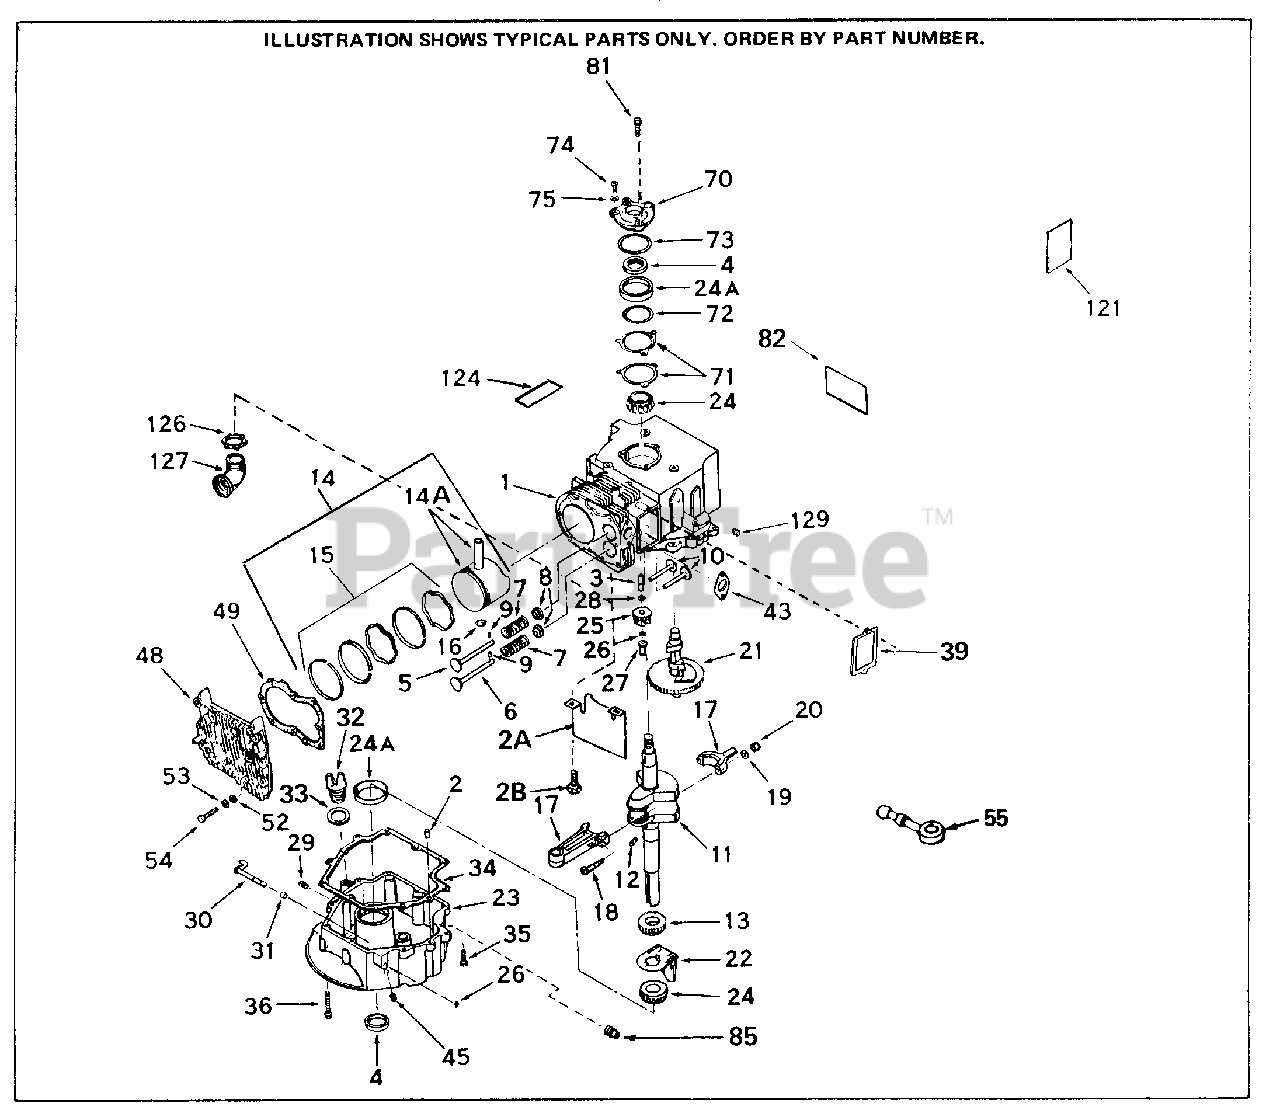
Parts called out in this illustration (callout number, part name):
1	"Cylinder (Incl. 2,2A,2B,3,4,82) 3-5/1 6" Bore
2	Dowel Pin
2A	Oil Baffle Not used in early product ion
2B	Screw, 10-24 x 1/2" Not in early pro d.
3	Shaft, Mechanical governor
4	Seal, Oil
5	Intake Valve (Std.)
5	Intake Valve (1/32" OS) (Incl. 8)
6	Exhaust Valve (Std.)
6	Exhaust Valve (1/32" OS) (Incl. 8)
7	Spring, Valve
8	Cap, Valve spring (Std.)
8	Cap, Valve spring (1/32" OS)
9	Pin, Valve spring retaining
10	Lifter, Valve
11	Crankshaft Incl. 12, 13, 22, 24 & 24 A
12	Pin, Crankshaft gear
13	Gear, Crankshaft
14	Piston, Pin & Ring Set (Std.) 3-5/16 " Bore
14	Piston, Pin & Ring Set (.010" OS)
14	Piston, Pin & Ring Set (.020" OS)
14	Piston, Pin & Ring Set (.040" OS)
14A	Piston & Pin Ass'y. (Incl. 16)(Std.) 3-5/16"
14A	Piston & Pin Ass'y. (Incl. 16) .010" OS
14A	Piston & Pin Ass'y. (Incl. 16) .020" OS
14A	Piston & Pin Ass'y. (Incl. 16) .030" OS
14A	Piston & Pin Ass'y. (Incl. 16) .040" OS
15	Ring Set (Std.) (3-5/16" Bore)
15	Ring Set (.010" OS)
15	Ring Set (.020" OS)
15	Re-Ringing Set, Piston
15	Ring Set (.030" OS)
15	Ring Set (.040" OS)
16	Ring, Piston pin retaining
17	Connecting Rod Ass'y. (Incl. 18,19,20 ) (Std.)
17	Connecting Rod Assy. (Incl. 18,19,20) . 010" OS
17	Connecting Rod Assy. (Incl. 18,19,20) . 020" OS
18	Screw, Connecting rod
20	Nut, Connecting rod, 5/16-24
21	Camshaft (MCR)
22	Dipper, Oil
23	Flange, Mounting (Incl. 4, 45 & 85)
24	Bearing, Tapered roller
24A	Cup, Bearing
25	Gear Assy., Governor
26	Retaining Ring
27	Spool, Governor
28	WASHER
29	Oil Drain Plug, 3/8-18
30	Rod Assy., Governor
31	Spacer, Governor rod
32	Oil Fill Plug (Incl. 312) also availa ble in Packaged Part #740079
33	Oil Fill Plug Gasket
34	Gasket, Mounting flange
35	Screw, 1/4-20 x 1"
36	Screw, 1/4-20 x 2"
39	Gasket, Breather
43	Gasket, Carburetor
45	Oil Drain Plug
48	Head, Cylinder
49	Gasket, Cylinder head
52	Washer, Flat
53	Washer, Belleville
54	Screw, 5/16-18 x 1-5/8"
70	Cover, Cylinder NOTE: Determine the gap between the cover and the machine d surface on the cylinder, which can be from .001" up to .007", in which c ase NO SHIM GASKETS WILL BE REQUIRED. Use of gaskets must be limited to a combined tot al of .010" t
71	Gasket, Shim (.004/.005 thick) NOTE: Determine the gap between the cover and the machined surface on the cylin der, which can be from .001" up to .0 07", in which case NO SHIM GASKETS WI LL BE REQUIRED. Use of gaskets must be limited to a combined t
71	Gasket, Shim (.005/.007 thick) NOTE: Determine the gap between the cover and the machined surface on the cylin der, which can be from .001" up to .0 07", in which case NO SHIM GASKETS WI LL BE REQUIRED. Use of gaskets must be limited to a combined t
72	Spacer, Steel (.010 thick) NOTE: Det ermine the gap between the cover and the machined surface on the cylinder, which can be from .001" up to .007", in which case NO SHIM GASKETS WILL B E REQUIRED. Use of gaskets must be l imited to a combined tot
73	"O" Ring
74	Screw, 5/16-18 x 7/8"
75	Washer, Lock, 5/16
81	Screw, 5/16-18 x 1-1/4"
82	Decal, Model & Serial Number
85	Plug, Pipe, 3/4-14
121	Decal, Instruction
124	Decal, Name & H.P.
126	Nut, Muffler
129	Oil Drain Plug adless)
